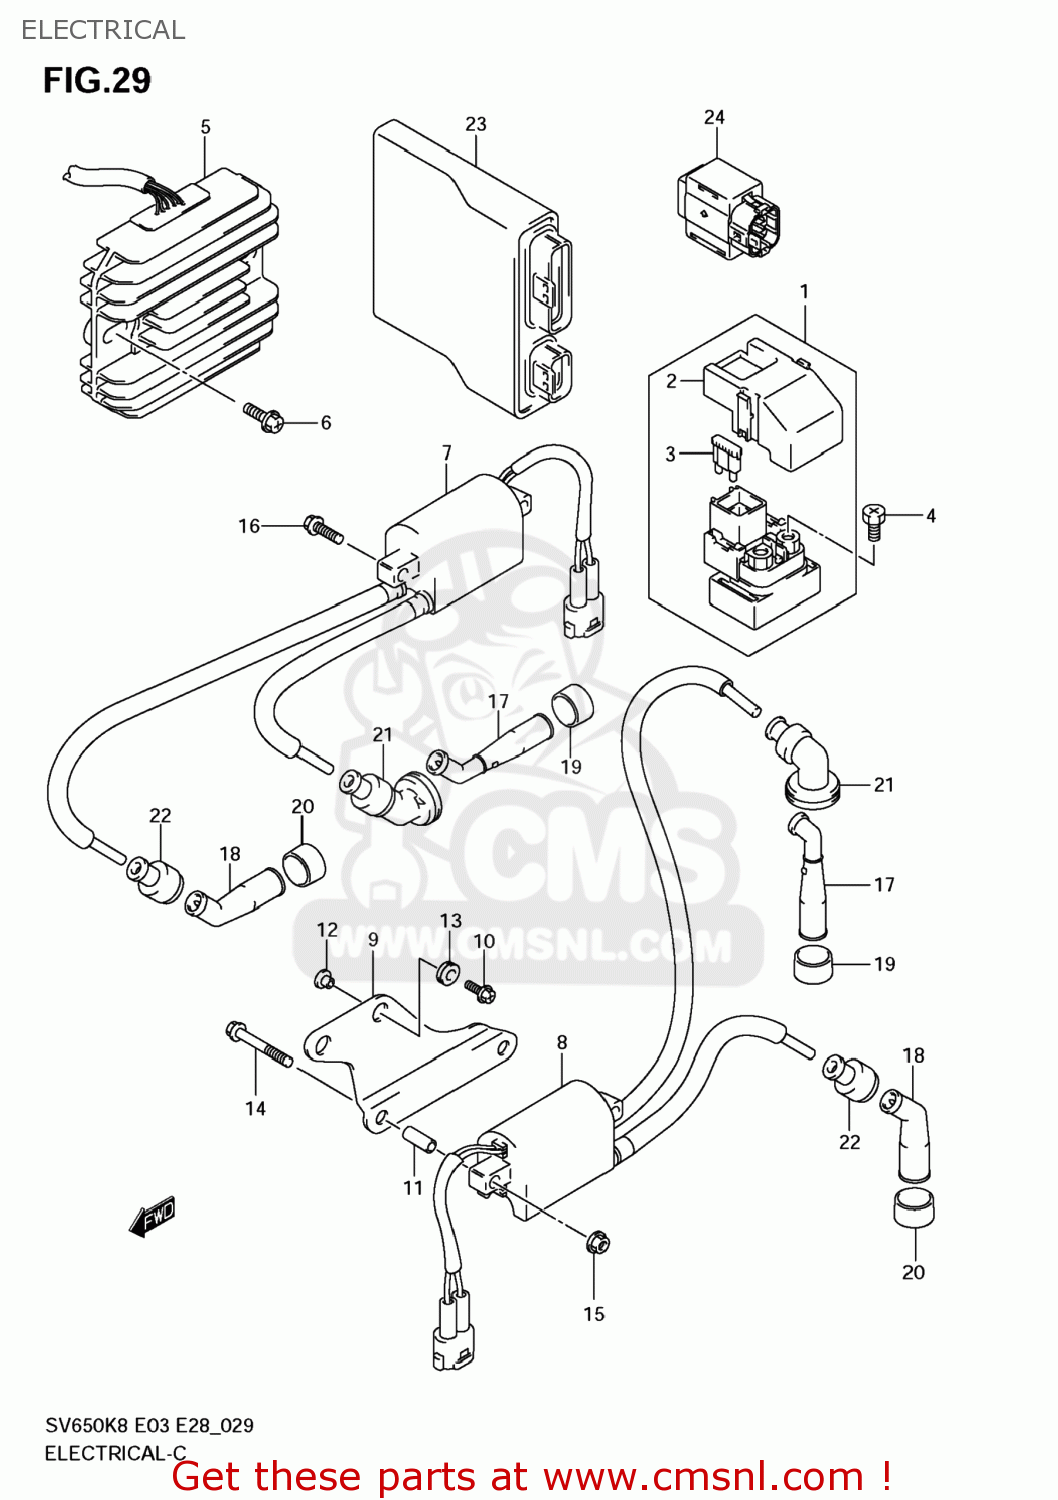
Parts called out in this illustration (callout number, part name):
1	RELAY ASSY,STARTING MOTOR
2	COVER
3	FUSE(30A)
4	SCREW(6X8)
5	RECTIFIER ASSY
6	SCREW
7	COIL ASSY,IGNITION FR
8	COIL ASSY,IGNITION RR
9	BRACKET,IGNITION COIL RR
10	BOLT(6X16)
11	SPACER(6.4X10X18)
12	SPACER(6.2X8.4X6.9)
13	CUSHION
14	BOLT
15	NUT
16	BOLT
17	CAP ASSY,SPARK PLUG
18	CAP ASSY,SPARK PLUG
19	SEAL,SPARK PLUG
20	SEAL,SPARK PLUG
21	SEAL,HIGH TENSION CORD CTR
22	SEAL,HIGH TENSION CORD
23	CONTROL UNIT,FI
24	SENSOR ASSY,FUEL CUT
